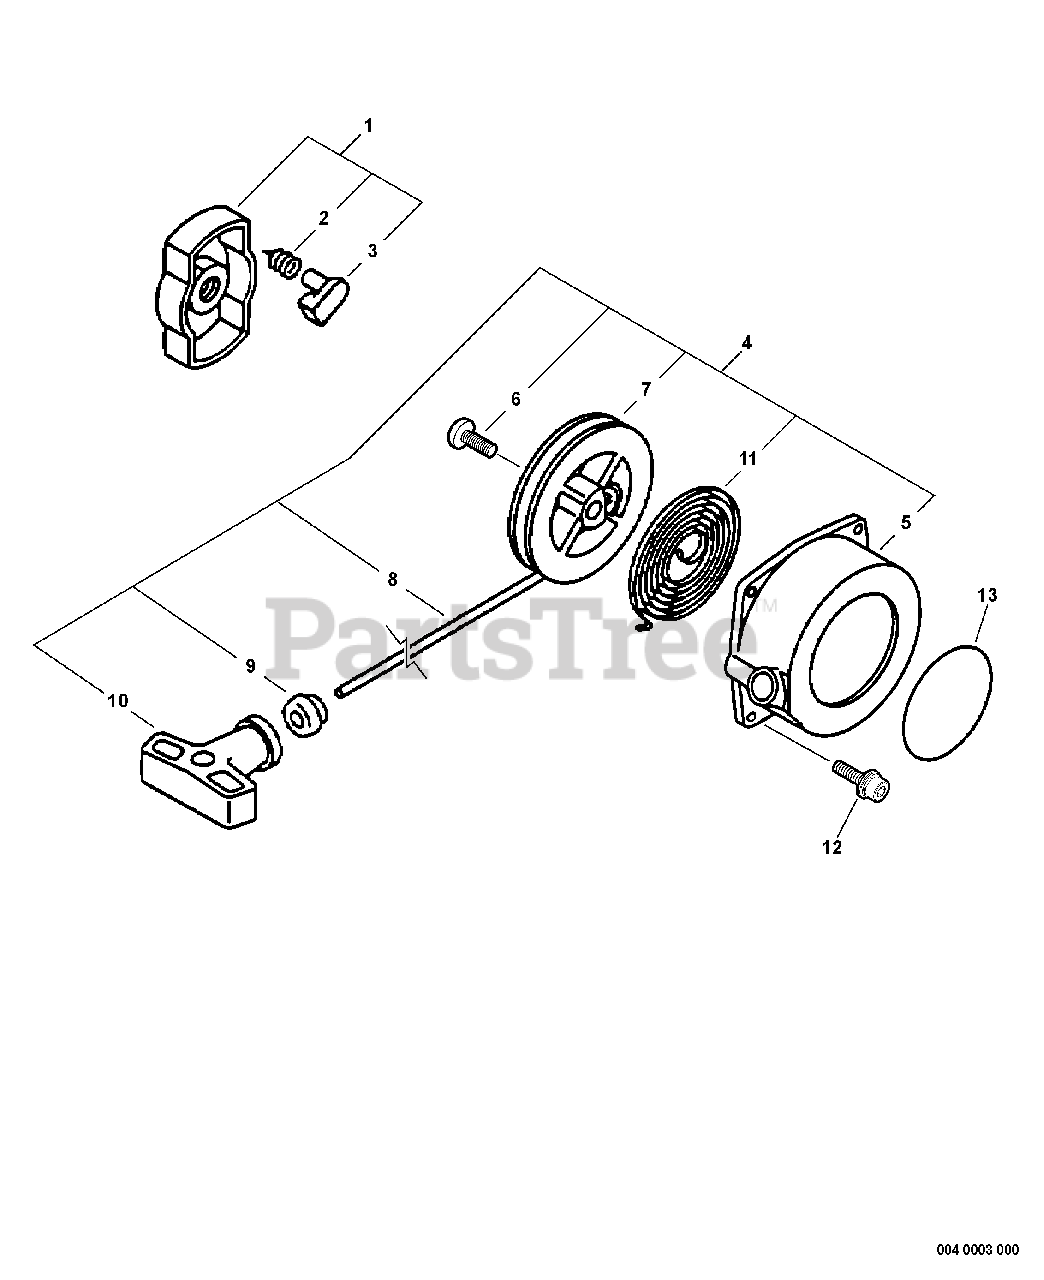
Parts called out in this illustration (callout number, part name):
1	PAWL ASSY, STARTER
2	SPRING, RETURN
3	PAWL, STARTER - BLACK
4	STARTER ASSY, RECOIL
5	CASE, RECOIL STARTER
6	SCREW
7	REEL, ROPE
8	ROPE, STARTER 3.0×1000
9	GUIDE, ROPE
10	GRIP, STARTER
11	SPRING, RECOIL
12	BOLT 4×16
13	LABEL, ECHO
